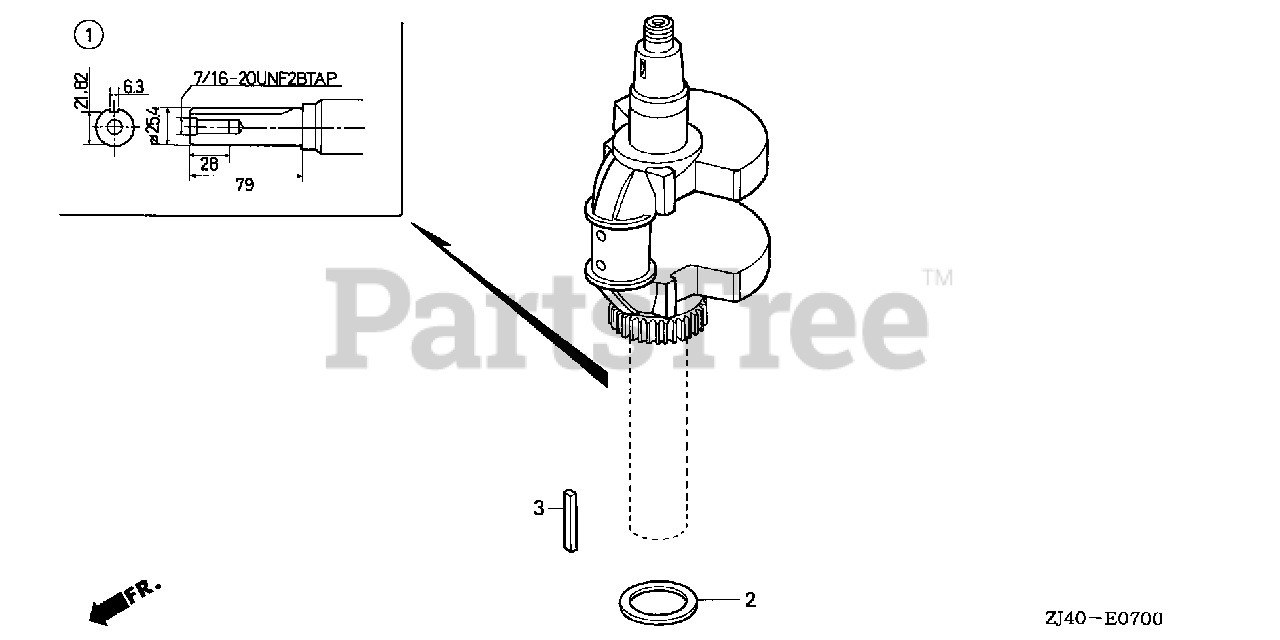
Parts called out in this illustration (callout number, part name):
1	CRANKSHAFT
2	WASHER, CRANKSHAFT THRUST (38.5X54.0X1.0)
3	KEY (6.3X6.3X43)
